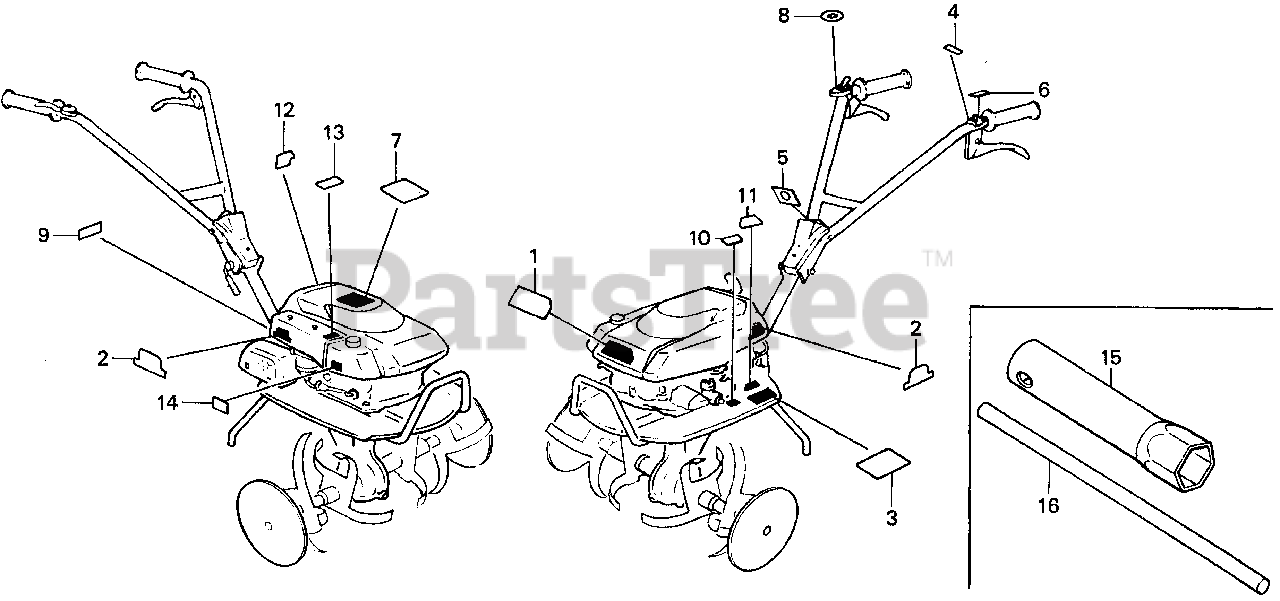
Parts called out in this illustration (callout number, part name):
5	MARK, SWITCH
6	CAUTION, CLUTCH LEVER (ENGLISH) (NOT AVAILABLE)
7	MARK, CAUTION
10	MARK, ENGINE OIL CAUTION
11	MARK, TRANSMISSION OIL CAUTION
12	MARK, STARTING INDICATION
13	LABEL, FIRE CAUTION
14	MARK, FUEL
15	WRENCH, SPARK PLUG
16	BAR A, HANDLE
